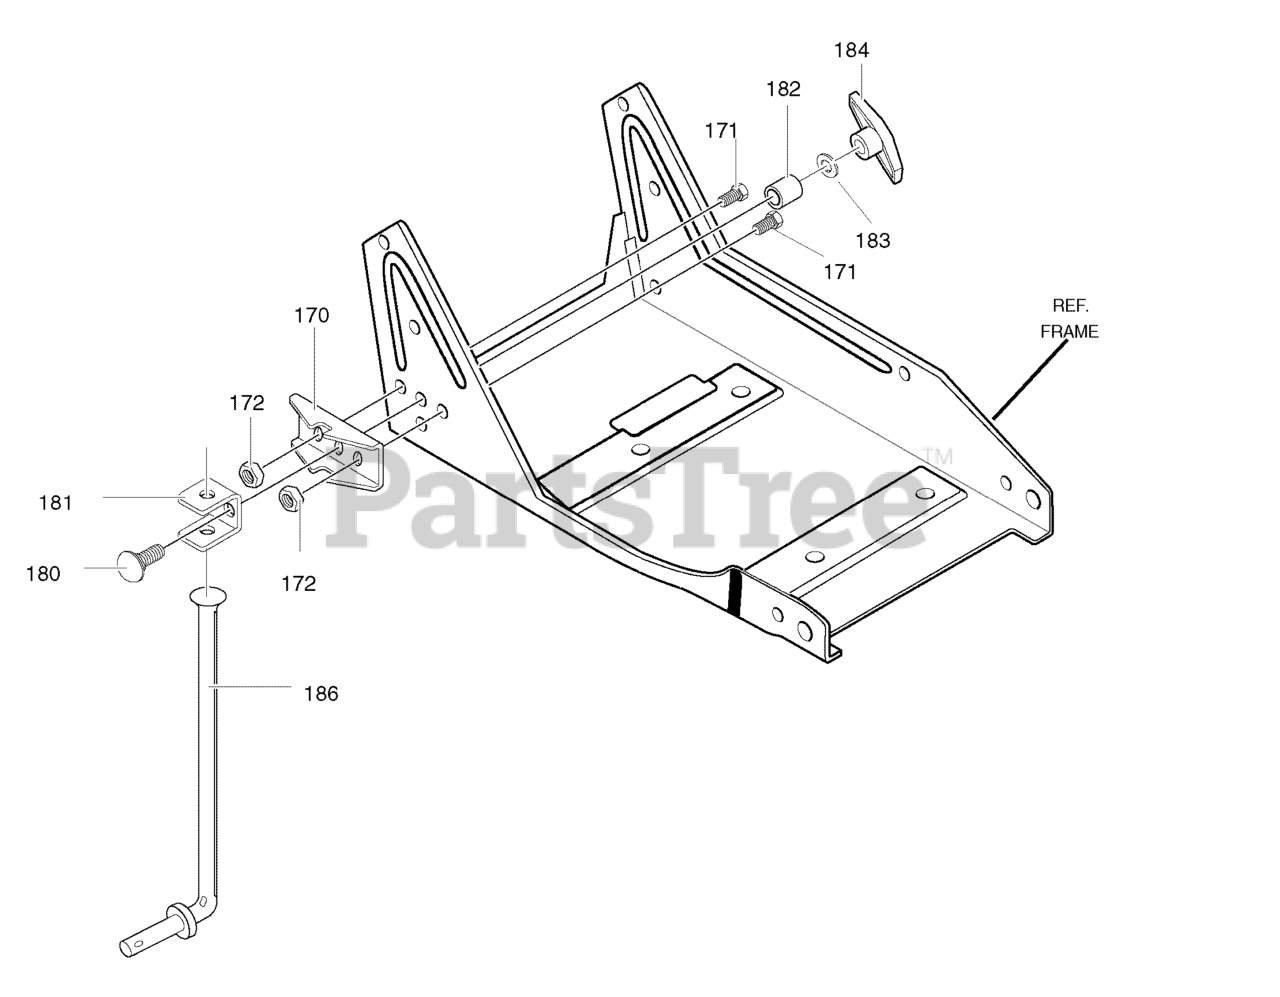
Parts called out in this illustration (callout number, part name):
170	BRACKET, Curb Hop Mount
171	SCREW, 5/16-18 x 0.75
172	NUT, 5/16-18
180	BOLT, 5/16-18x2.00
182	SPACER, Sleeve
183	FLATWASHER
184	KNOB, Wing 5/16-18
186	ROD, Wheel Support
